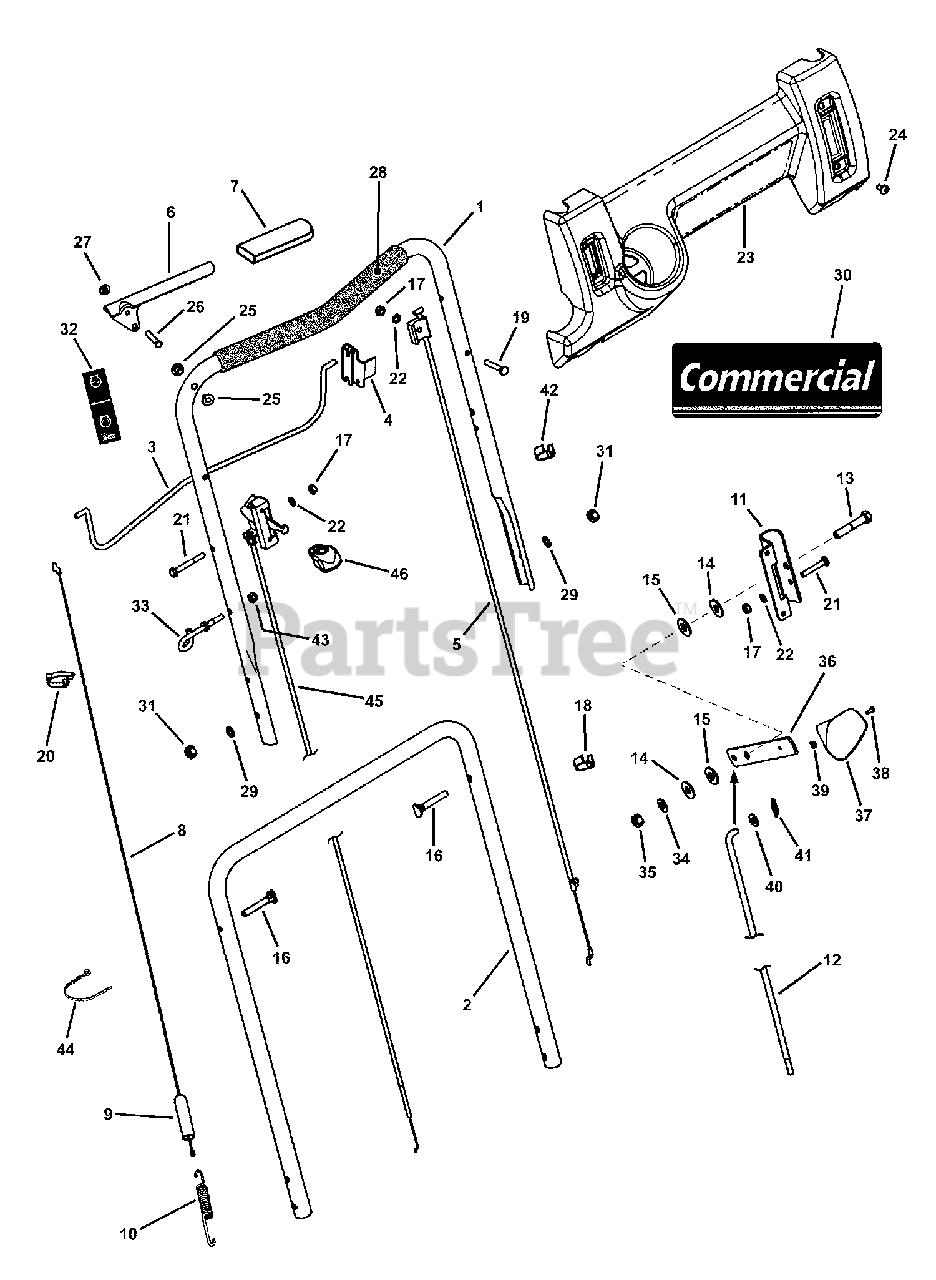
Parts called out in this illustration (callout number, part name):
1	HANDLE, Upper
2	HANDLE, Middle
3	BAIL, OPC Control
4	CLIP, Zone Control
5	CABLE, Zone Control (56-5/16" Long)
5	CABLE, Zone Control (49.98" Long)
5	CABLE, Zone Control (60.3" Long)
6	HANDLE, Clutch
7	COVER, Grip, Black 1.125"
7	GRIP, International Symbol, Black 4.6"
8	CABLE, Clutch Control (41-1/4" Long)
9	COVER, Vinyl
10	SPRING, Clutch- 21S
11	BRACKET, Shift
12	ROD, Speed Control (1/4-28 thread)
13	SCREW, 3/8-16 x 2" Hex Head Cap, GR 5
14	WASHER, 7/16" Flat
15	WASHER, Nylon
16	BOLT, 5/16-18 x 1-1/2" Curved Head
17	NUT, 1/4-20 Hex
18	CLIP, Wiring Harness
19	SCREW, 1/4-20 x 1-1/2" Hex Head Cap GR5
20	CLAMP, 7/8" Double Cable
21	SCREW, 1/4-20 x 2" Hex Head Cap, GR 5
22	WASHER, 1/4" Internal Tooth Lock
23	CONTROL PANEL (w/o Electrical Switch Hole)
24	SCREW, 1/4-20 x 1/2" Pan Head Self-Tap (Torx)
25	BUSHING, .27 x .35 x .4 Flange
26	PIN, 1/4 x 1-1/2"
27	PUSH-NUT, 1/4"
28	FOAM GRIP, 18.75" long
29	WASHER, 5/16" Internal Tooth Lock
30	DECAL, Commercial, Control Panel
31	NUT, 5/16-18 Hex, GR 5
32	DECAL, OPC Bail (International Symbol)
33	GUIDE, Rope (1/4-20 thread)
34	WASHER, Belleville
35	NUT, 3/8-16 Hex Center Lock
36	LEVER, Shift
37	KNOB, Shift
38	SCREW, #8-32 x 1/2" Cross Recess Filister Head Machine
39	NUT, #8-32 Hex
40	WASHER, 3/8" Flat
41	COTTER PIN, 5/16 Self Lock
42	TIE, Wire, 1.29 long, black
43	NUT, 1/4-28 Hex Nyloc
44	CABLE-TIE, 7"
45	THROTTLE CONTROL, 5.5 HP, Honda (50.81" long)
45	THROTTLE CONTROL, 6.0 HP Kawasaki (53.25" long)
46	THROTTLE KNOB
